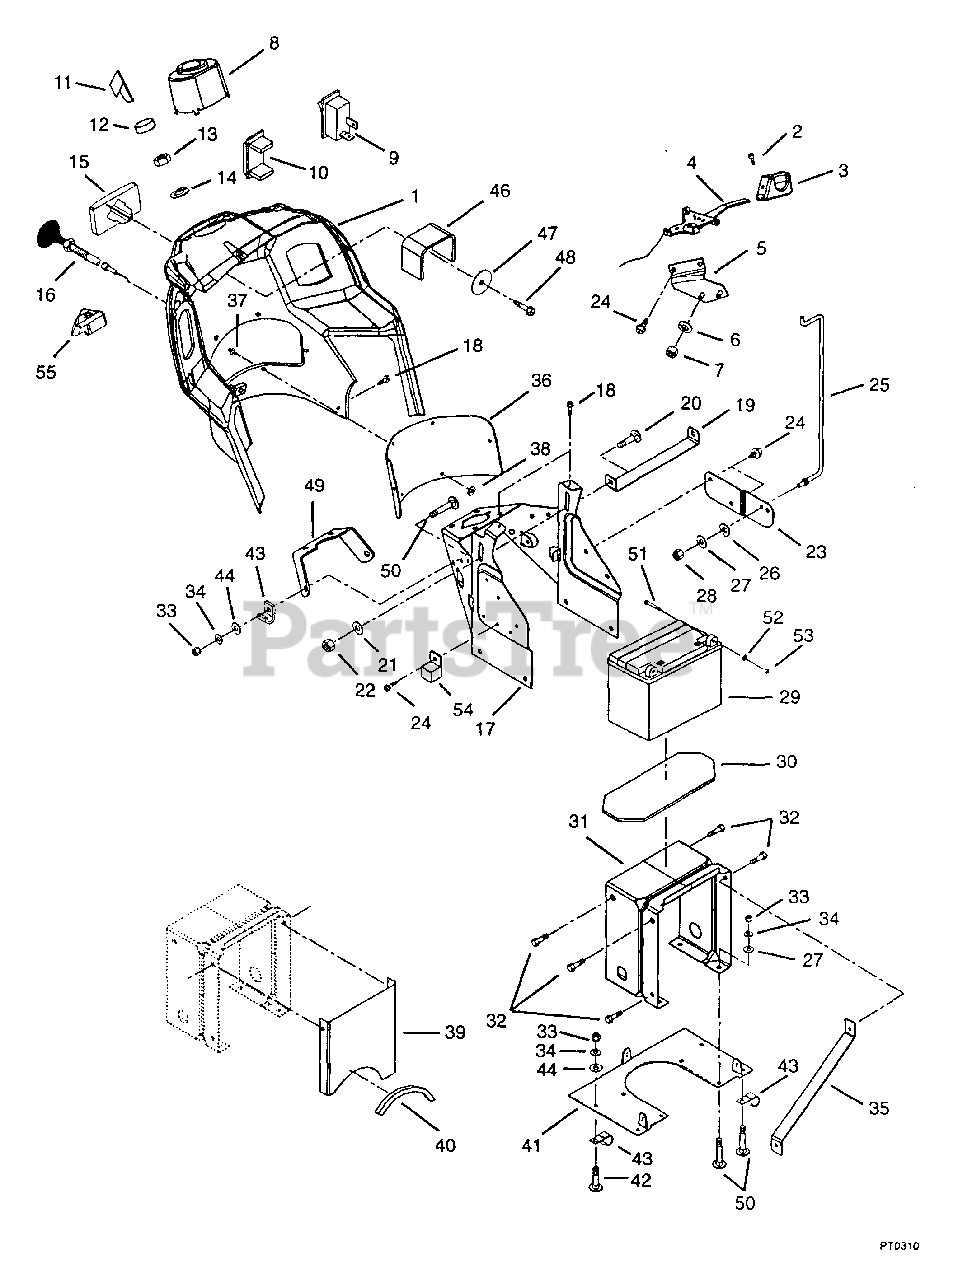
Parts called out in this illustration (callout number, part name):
2	SCR-SET 10-24X.38 UNC-3A
3	KNOB - THROTTLE
4	THROTTLE CONTROL-B&S
5	BRACE-THROTTLE CONTROL
6	WSHR-FL-STL .323X.625X.062 PL
7	NUT-LK-CTR .250-20 PL
8	STEERING CONE
9	SWITCH - LIGHT
10	COVER - SWITCH
11	KEY -W/CAP
12	CAP - IGNITION SWITCH
13	NUT- PANEL .562-24 GRECO
14	WSHR-LK-INT .563X.040 PL
15	KNOB - FILLER
16	CHOKE CABLE
17	SUPPORT - DASH - TOP
18	SCR-TAP 10-24X.484 HWH TR
19	HOLDDOWN - BATTERY
20	BLT-RDHDSQNK .312-18X.62 PL
21	WSHR-FL-STL .323X.625X.062 PL
22	NUT-LK .312-18 GR A PL
23	MOUNT - PROP ROD
24	SCR-TAP .250-20X.37 HWH PL TR
25	ROD - HOOD PROP
26	WAVE WASHER .390X.655X.110
27	WSHR-FL-STL.312X.734X.065PL
28	NUT-LK-CTR .250-20 PL
29	BATTERY
30	RUBBER PAD
31	SUPPORT DASH BASE
32	SCR-TAP .312-18X.50 HWH PL TR
33	NUT-HEX .312-18
34	WSHR-LK .312X.097 PL HVY
36	SCREEN - DASH
37	RETAINER, RADIATOR SHROUD
38	WSHR-FL-STL .265X.500X.087 PL
39	SHIELD, AIR
40	TAPE-ADHESIVE BACKED FOAM
41	SUPPORT, DASH BASE (G.S. ONLY)
42	BLT-RDHDSQNK .31-18X.75 GR5 PL
43	J-CLAMP
44	WSHR-FL-STL.344X.688X.065PL
45	KNOB - FILLER
46	SPACER-CHANNEL
47	WSHR-FL-STL .281X1.250X.048 BL
48	SCR-TAP .250-20X.75 HWH PL TR
50	BLT-HEX .31-18X.75 PL GR2
51	BLT-HEX .25-20X.75 PL GR5
52	WSHR-LK .250X.077 HVY PL
53	NUT-HEX .250-20 PL
54	RELAY
55	PTO KNOB/ SWITCH ASSY
